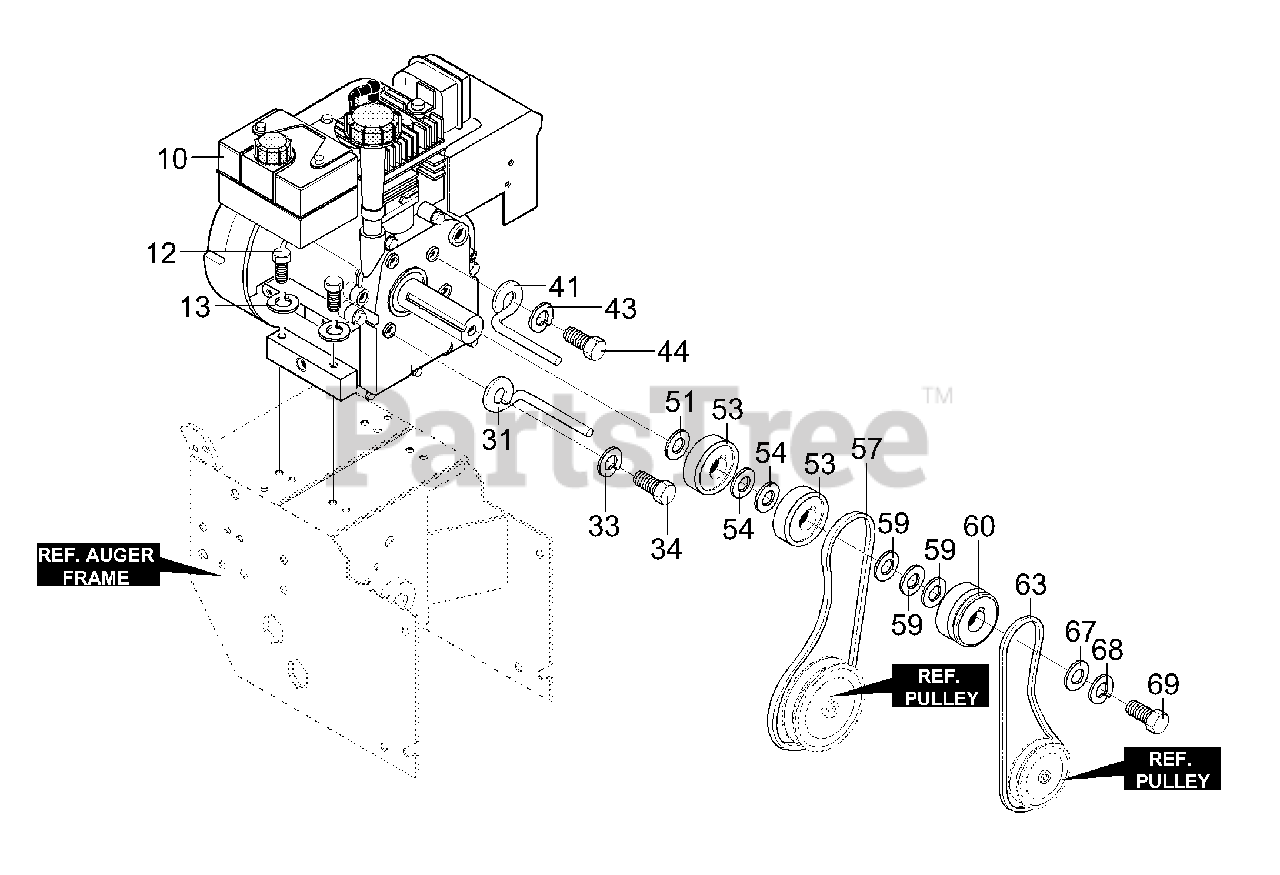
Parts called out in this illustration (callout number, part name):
10	ENGINE 9HP TEC
12	SCREW, 5/16-18 X 1.50
13	WASHER, HVSPTLK .328X.60X.09
31	GUIDE, ROD BELT RH
33	WASHER, HVSPTLK .328X.60X.09
34	SCREW 5/16-24X.625
41	GUIDE, ROD BELT LH
43	WASHER, HVSPTLK .328X.60X.09
44	SCREW 5/16-24X.625
51	WASHER, CRANKSHAFT
53	PULLEY, HALF V3L 2.00X.752ID
54	FLATWASHER, .752X.91X.02
57	BELT, V 3L 33.13LG
59	FLATWASHER, .765X1.12X.06
60	PULLEY, ENGINE V 4L
63	BELT, V 4L 36.6LG
67	FLATWASHER
68	WASHER, REGSPTLK .393X.60X.10
69	SCREW 3/8-24 X 1.00 NYL
